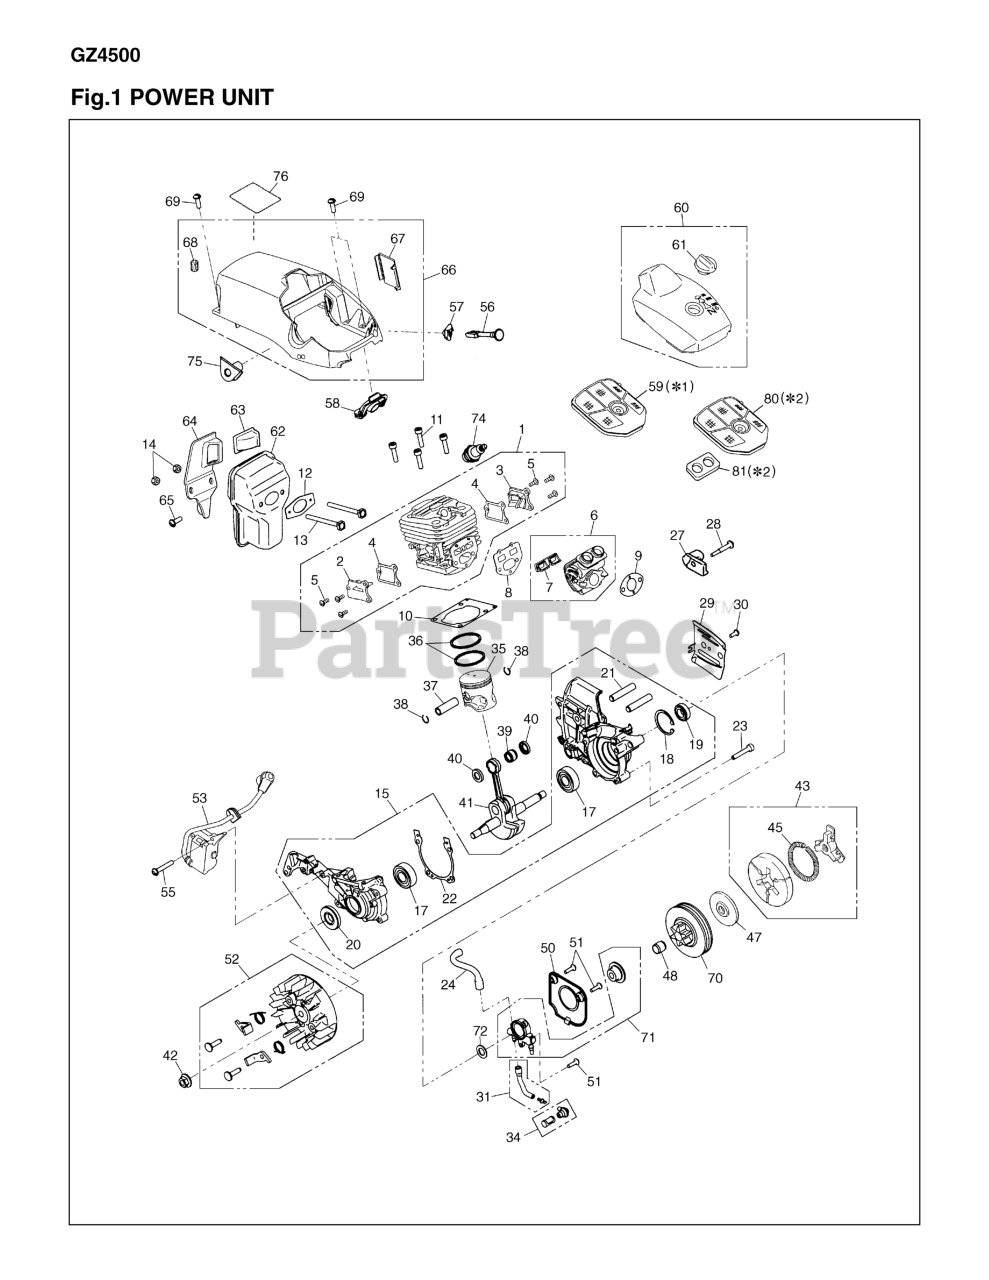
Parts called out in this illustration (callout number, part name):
1	CYLINDER ASSY
2	TR COVER MAG
3	TR COVER PTO
4	GASKET
6	INSULATOR
7	SEAL
8	GASKET
9	GASKET
10	GASKET
11	BOLT (RPLS 2850-14220)
12	GASKET, MUFFLER
13	BOLT, MUFFLER
14	NUT, MUFFLER (RPLS 3356-15230
15	CASE ASSY
17	BEARING
18	RING, SNAP, M32 x 1.2
19	SEAL, OIL (RPLS 1100-21210)
20	SEAL
21	STUD (RPLS 0205-50825)
22	GASKET
23	BOLT
24	PIPE
27	CATCHER
29	PLATE (A)
31	PIPE IN COMP.
34	FILTER COMP
35	PISTON
36	RING
37	PIN
38	RING, SNAP
39	BEARING
40	WASHER
41	SHAFT COMP
43	CLUTCH ASSEMBLY
45	SPRING
47	PLATE
48	BEARING
50	COVER, PUMP
51	SCREW
52	ROTOR COMP
53	COIL ASSY
55	SCREW
56	ROD, CHOKE
57	GROMMET, CHOKE
58	GROMMET, THROTTLE
59	CLEANER ASSY
60	COVER COMP
61	KNOB (RPLS 3356-83322)
62	MUFFLER
63	ARRESTER, SPARK
64	STAY
65	SCREW (REPLACES 2616-24320)
66	COVER COMP
68	GROMMET (RPLS-31151)
69	SCREW
70	DRUM 0.325-7
71	OIL PUMP SET(RPLS 848C1067A4)
72	THRUST WASHER
74	SPARK PLUG
75	GROMMET
81	CLEANER COMP
NI	PIN
NI	PIPE
NI	PIPE IN
NI	JOINT
NI	SHOE
NI	BOSS
NI	OIL PUMP
NI	WORM
